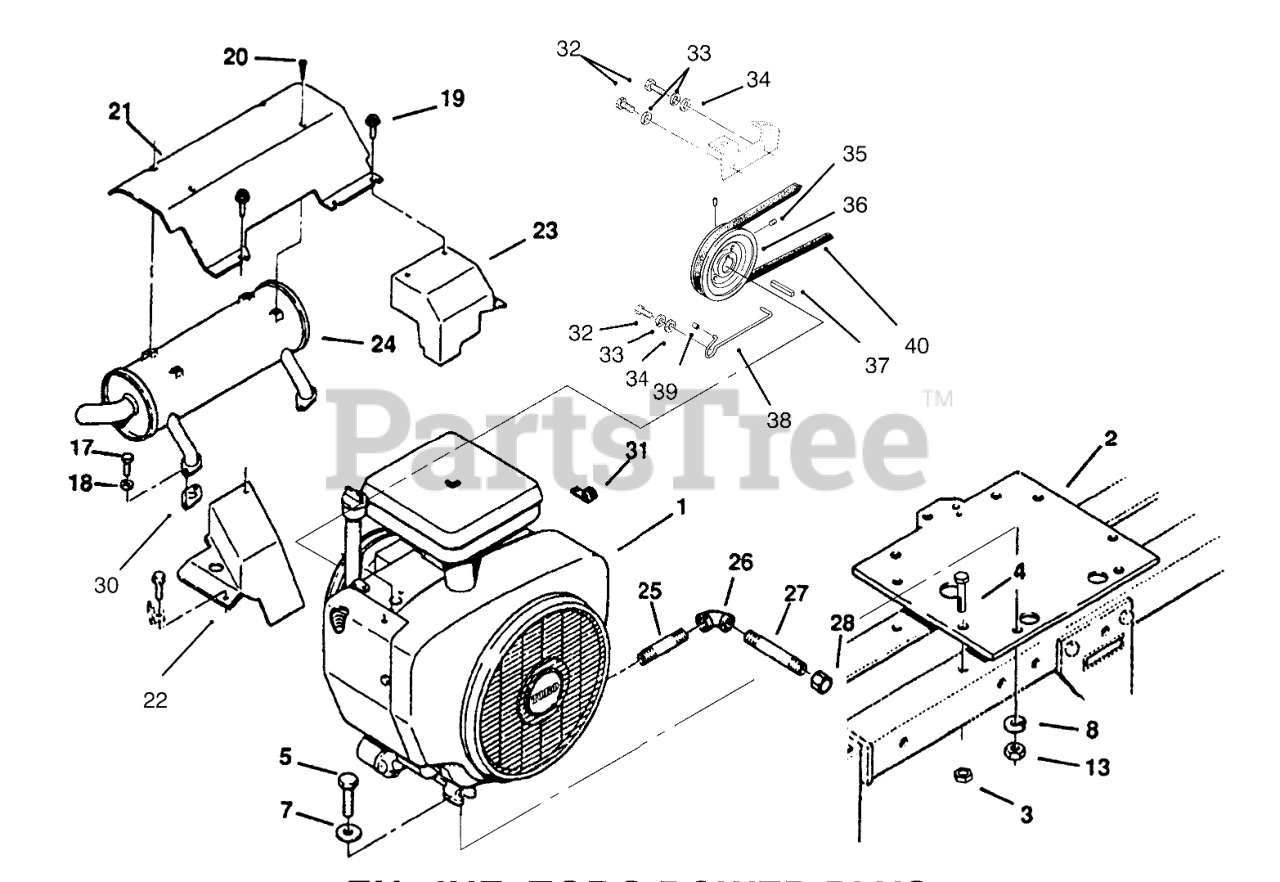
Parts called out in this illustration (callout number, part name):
1	Engine-16HP TORO Power Plus P216G-I/10976D
2	PLATE-ENGINE B
3	NUT-LOCK, NI
4	SCREW-HH
5	SCREW-HH
7	WASHER-FLAT
8	WASHER-LOCK
13	NUT-HEX
17	SCREW-HH
18	WASHER-LOCK
19	SCREW
20	Screw
21	Air Deflector
22	LH Exhaust Cover
23	RH Exhaust Cover
24	MUFFLER-EXHAUST
25	Pipe
26	ELBOW 3/8 90 DEG
27	PIPE-NIPPLE 3/8 X 4"
28	Cap
30	GASKET
31	J-CLIP
32	SCREW-HH
33	WASHER-LOCK
34	WASHER-FLAT
35	SCREW-SET, HSH
36	PULLEY
38	GUIDE BELT
40	BELT-V
